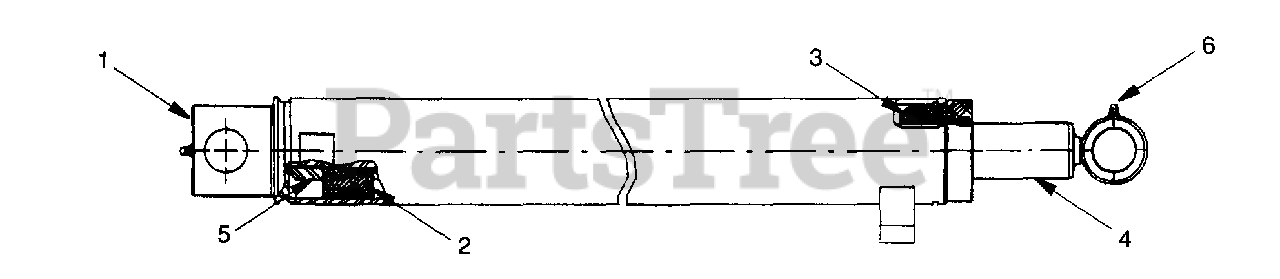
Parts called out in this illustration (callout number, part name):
1	Complete Assembly (Rod O.D. 1.00)
1	Complete Assembly (Rod O.D. 1.12)
2	Piston (used with WM-56446)
2	Piston (used with WM-46670)
3	Head Gland (used with WM-56446)
3	Head Gland (used with WM-46670)
4	Rod (used with WM-56446)
4	Rod (used with WM-46670)
5	Locknut (used with WM-56446)
5	Locknut (used with WM-46670)
6	Lube Fitting
